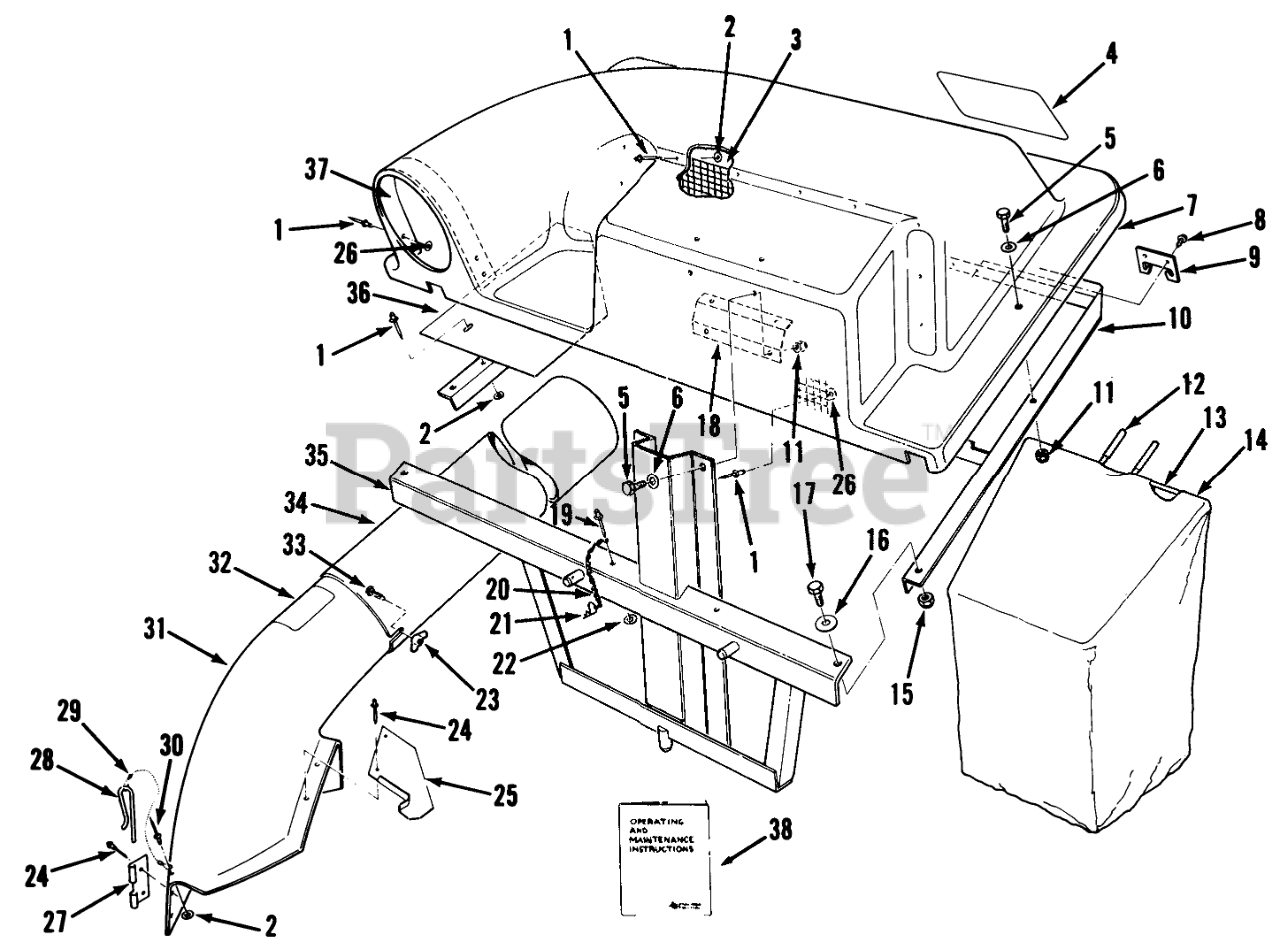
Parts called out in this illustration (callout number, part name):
1	RIVET-POP
2	WASHER-PLAIN
3	SCREEN
4	DECAL-BAGGER, TWIN
5	SCREW-HH
6	WASHER-PLAIN
7	COVER-BAGGER, TWIN
8	Bolt 1/4-20
9	BRACKET-FRAME, BAG
10	Cover-Frame
11	NUT-LOCK, NI
12	GRIP-HANDLE, BAG
13	Frame-Bag
15	NUT-LOCK, NI
16	WASHER-FLAT
17	SCREW-HH
18	Plate-Backup
20	10 LINK CHAIN W/O HOOK
21	PIN-HAIR
22	WASHER-BACK
23	NUT-WING SPECL
24	RIVET-BLIND
25	CHUTE SUPT BRKT
26	WASHER-FLAT
27	Bracket-Chute Mounting
28	PIN-LOCKING, CHUTE
29	LANYARD
30	Rivet-Pop 3/16 x 1/4
31	Chute Assembly (Includes Reference #24-30 & 32)
32	DECAL-DANGER
33	Carriage Bolt 1/4-20 x 3/4
34	TUBE(ROUND&LONG)
35	Frame-Mounting
36	Baffle
37	Support Inlet
38	OPERATORS MANUAL
